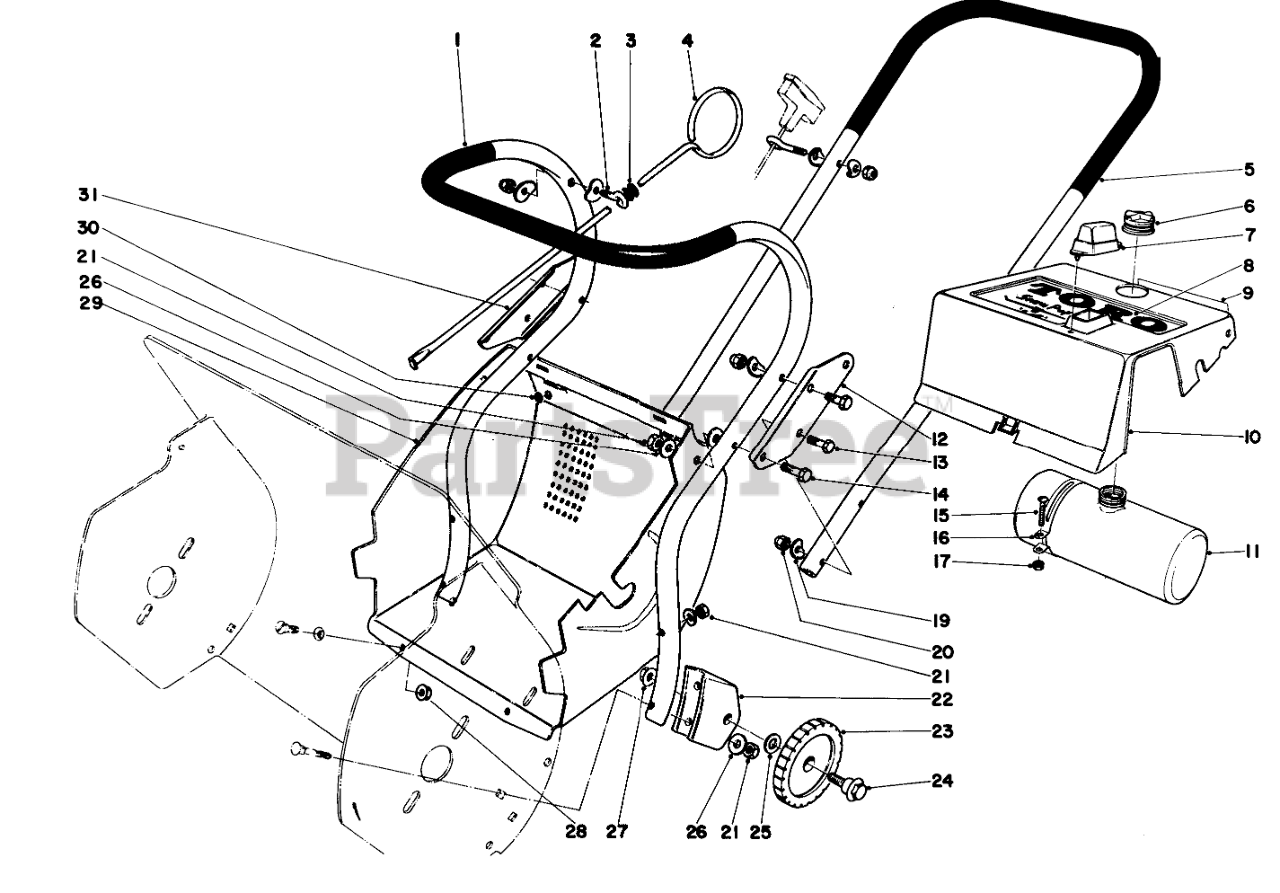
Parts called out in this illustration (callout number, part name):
1	Handle Lower
2	Bolt-Eye
3	GROMMET
4	Vane Adj. Rod
5	Handle Upper
6	Gas Cap
8	Decal
9	Decal
10	Shroud Incl. Ref. #7
11	Gas Tank Assy. Incl. Ref. #6
12	SPLICE PLATE
15	10-24 X 1 RND HD MS
16	1/2 GAS TANK CLAMP
17	NUT-SQ
19	WASHER
20	NUT-CAP
21	Nut
22	Bracket Wheel
23	Wheel
24	Bolt-Shoulder
25	WASHER-PLAIN
26	WASHER-FLAT
27	NUT-HHF
28	NUT-LOCK, FLANGE
29	Lower Shroud
30	SNO PUP PLATED EYELET
31	Plate-Splice
